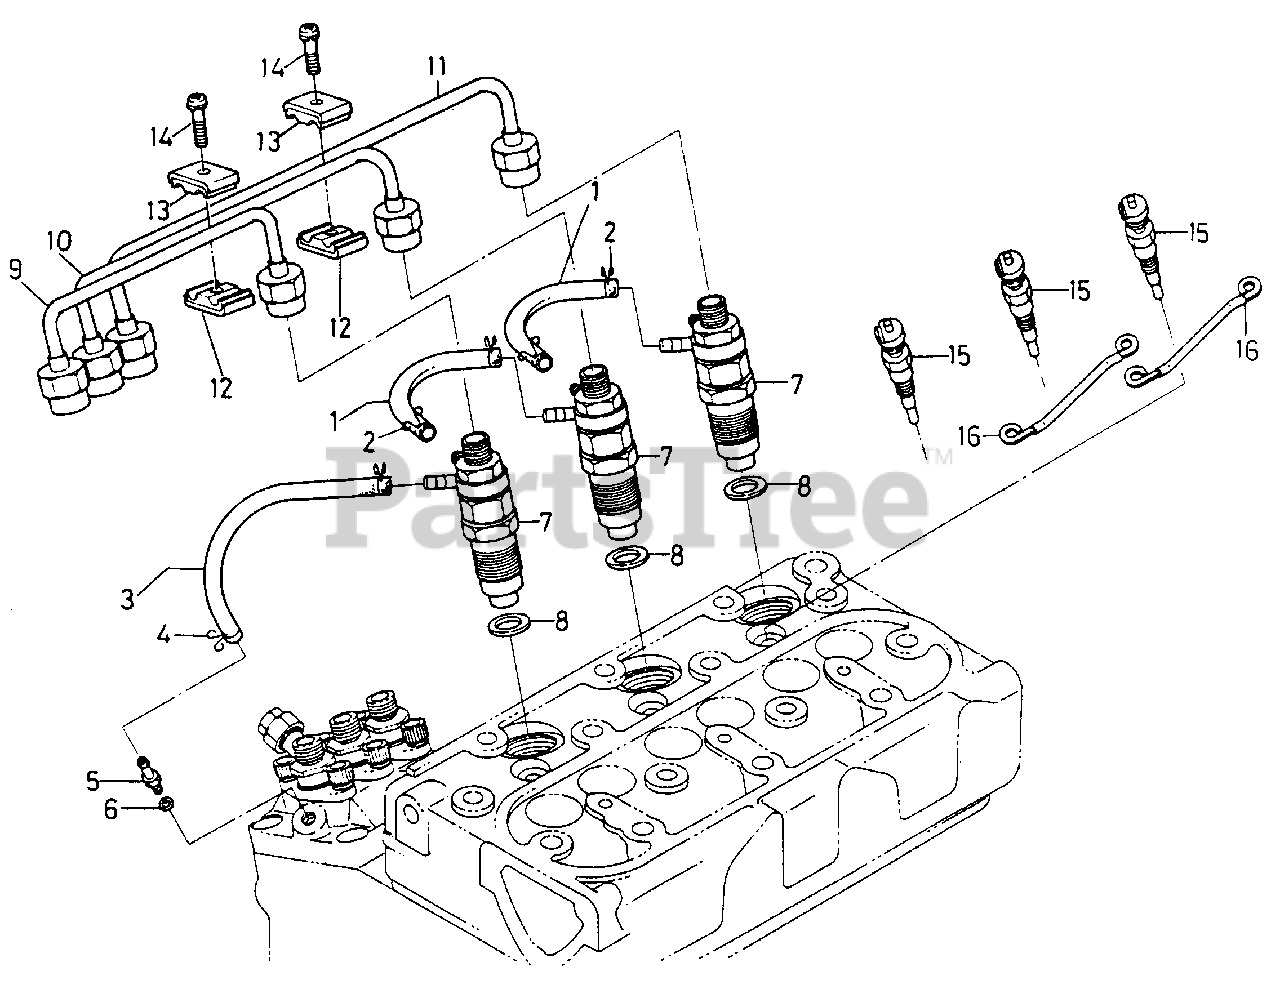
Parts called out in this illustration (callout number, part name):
1	Pipe, Overflow
3	Pipe, Overflow
7	Nozzle, Injection
8	Washer
9	Pipe, Injection 1
10	Pipe, Injection 2
11	Pipe, Injection 3
12	Clamp, Pipe 1
13	Clamp, Pipe 2
14	Screw, M5 X 20 Class 4.8 P/Hdcr
15	Plug, Glow
16	Wire, Glow Plug
